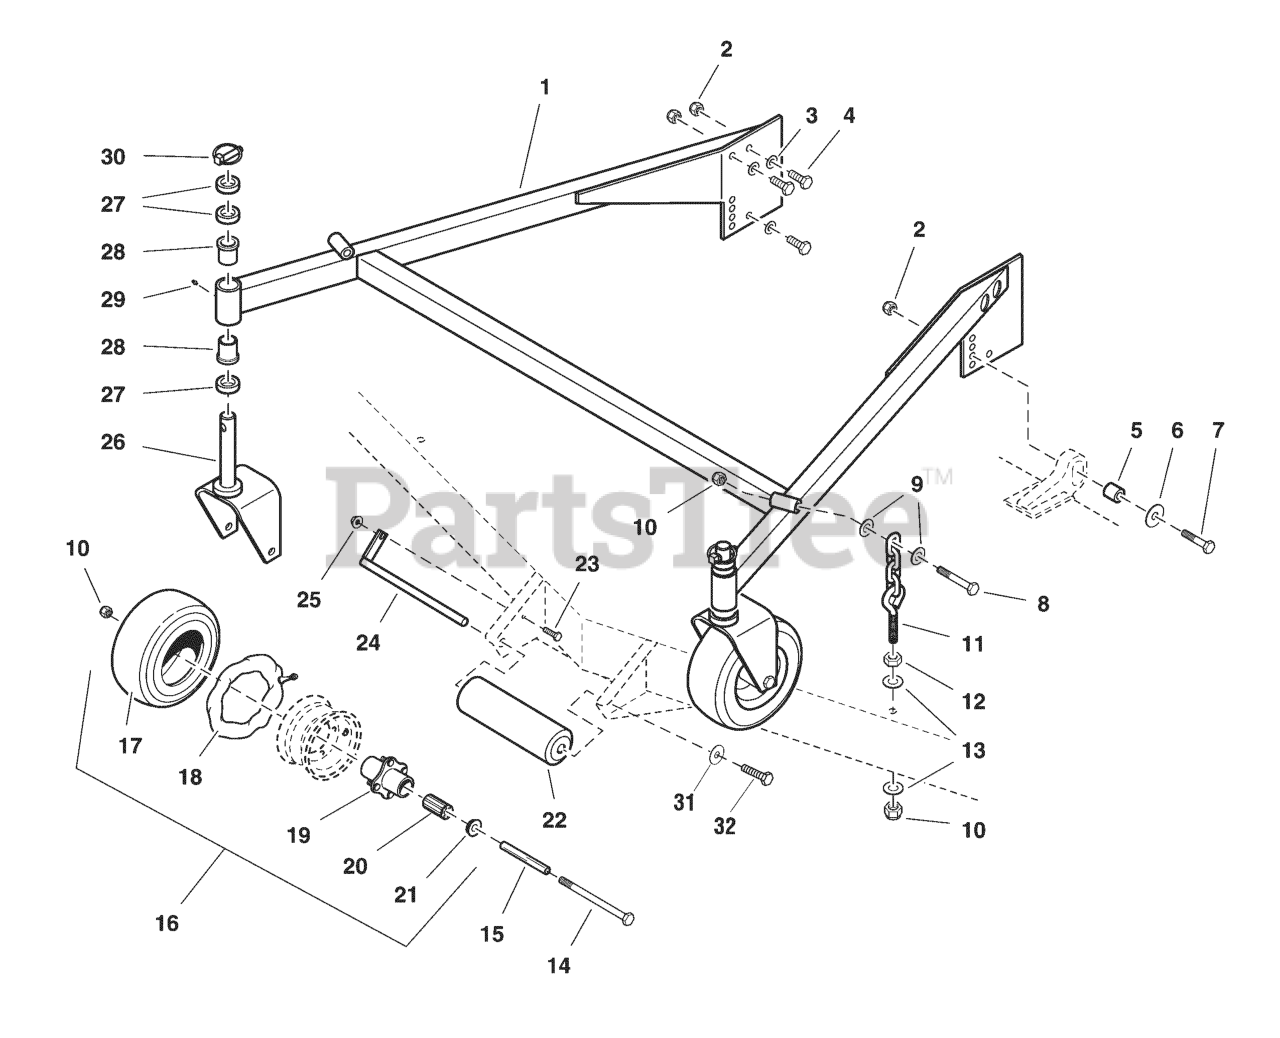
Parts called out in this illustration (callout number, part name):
1	CASTER MOUNT FRAME, Complete
2	NUT, Hex, Nylon Lock, 1/2-20
3	WASHER, 1/2 SAE
4	BOLT, 1/2-20 X 1-1/4" GD5 CZ
5	DECK MOUNT SPACER
7	BOLT, 1/2-20 X 2-1/2" GD5 CZ
8	BOLT, 1/2-13 X 3-1/2, HEX HD, GD5, CZ (SV)
9	WASHER, 1/2 SAE
10	NUT, 1/2-13 HEX NYLON LOCK
11	DECK HANGER
12	NUT, 1/2-13 Hex
13	WASHER, 1/2" USS
14	BOLT, 1/2-13 x 5-1/2
15	AXLE, Caster Wheel
16	TIRE ASSM, 9 X 3.5 X 4, SILVER
16	WHEEL & TIRE ASSEMBLY, White, 9 x 3.5 x 4, Complete
17	TIRE, Front, 9 x 3.5 x 4
19	HUB & BEARING ASSEMBLY, Complete, Silver
19	HUB & BEARING ASSEMBLY, Complete, White
20	BEARING, ROLLER 3/4" ID X 3.25" (ONE PER TIRE)(SV)
21	RETAINER, Bearing
22	Mower Seat
23	BOLT, 3/8-16 X 3/4" GD5 CZ
25	NUT, 3/8-16 Hex Serrated Flange
26	YOKE, Caster
27	SPACER, 1.02 x 1.56 x .50
28	BUSHING, FLANGE
29	GREASE FITTING
30	PIN, Lynch
31	WASHER, .390 X 1.50 X .109 YZ
32	BOLT, 3/8-16 X 1" GD5 CZ
